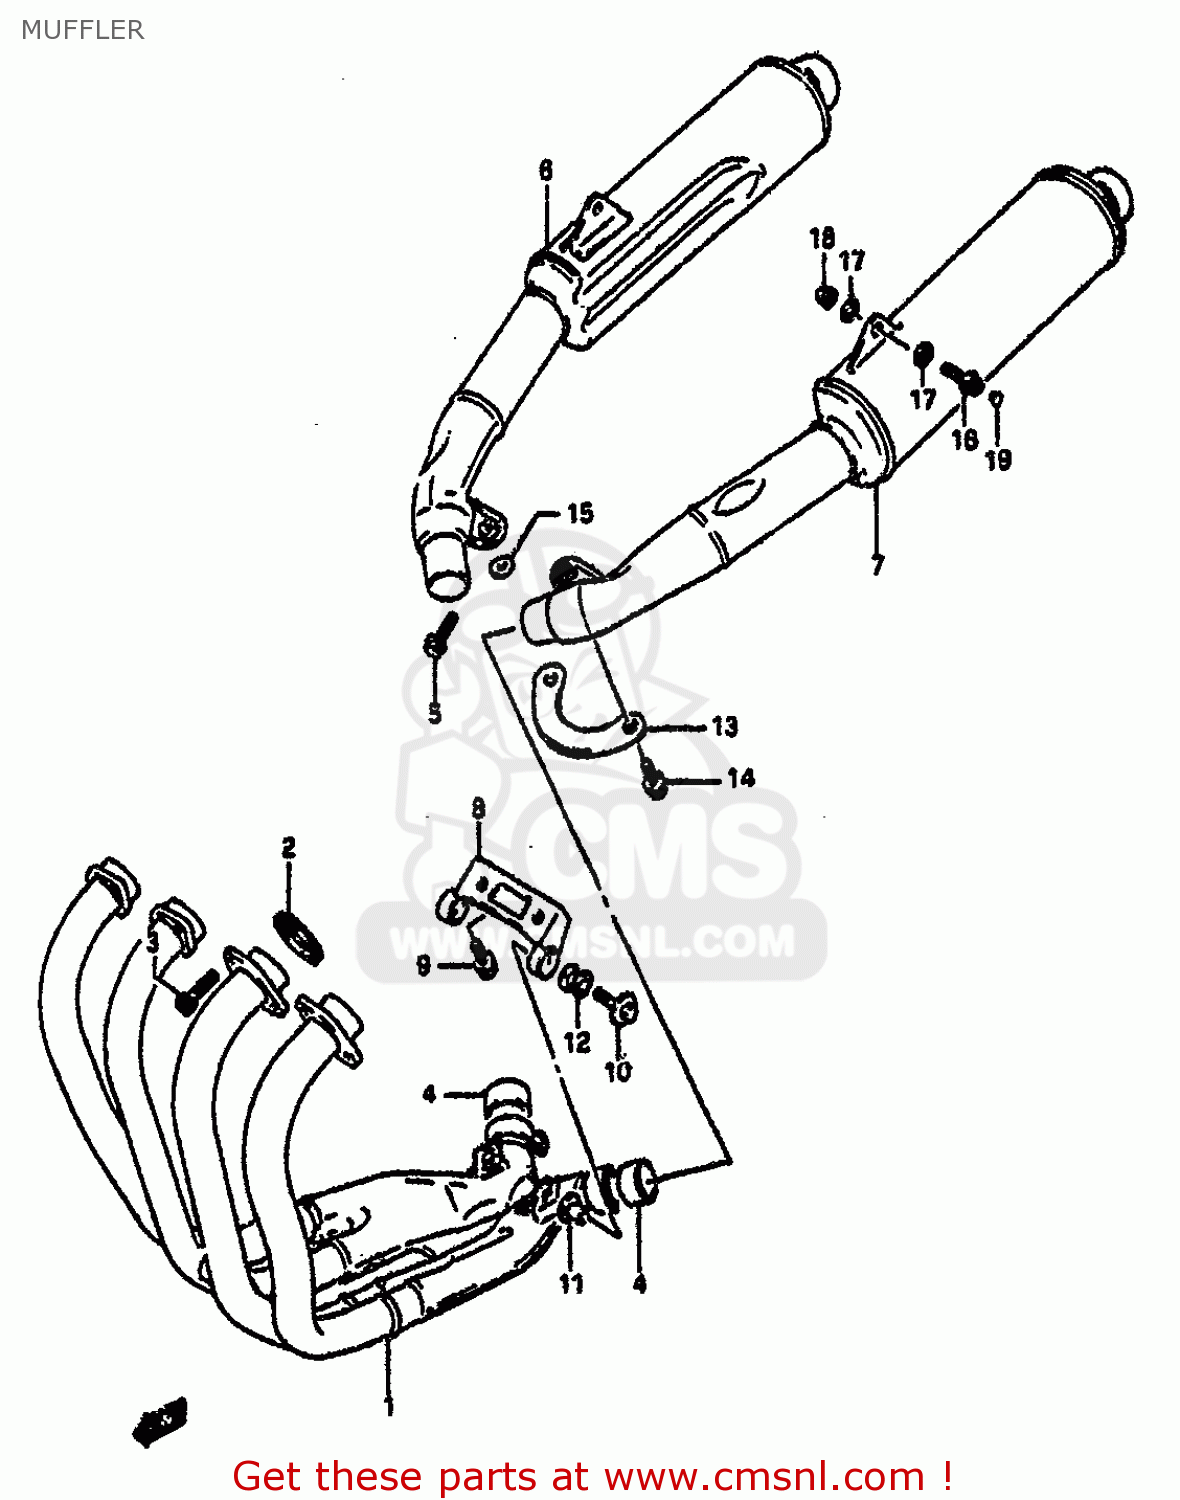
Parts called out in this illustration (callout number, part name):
1	EXHAUST ASSY
2	GASKET,EXHAUST PIPE (NAS)
3	BOLT
4	CONNECTOR,MUFFLER
5	BOLT 8X40
6	MUFFLER, RH
7	MUFFLER, LH
8	DAMPER,MUFFLER SUPPORT CTR
9	BOLT(8X20)
10	BOLT(8X35)
11	SPACER(8.6X12X18.5)
12	CUSHION
13	PLATE,MUFFLER JOINT
14	BOLT
15	WASHER (8.5X29X1.6)
16	BOLT
17	WASHER (10.5X24X2.3)
18	NUT
19	CAP(OD:12)
